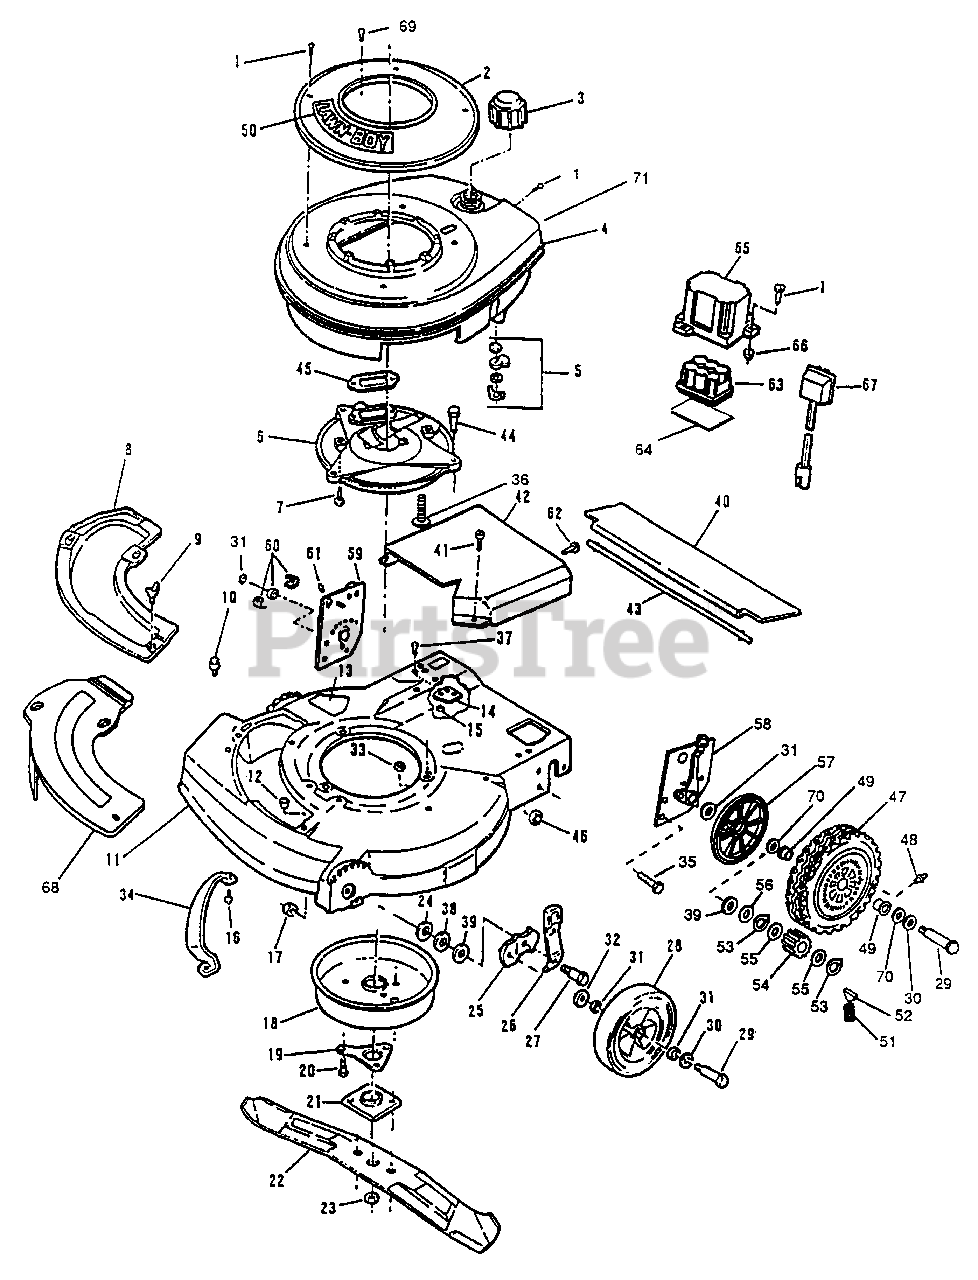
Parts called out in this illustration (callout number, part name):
1	Screw
2	Starter Base & Nut Assembly
3	Fuel Cap
4	Shroud-Engine (Inc. 5)
5	Fuel Shut-Off Assembly
6	Plate Muffler
7	Screw-Muffler Plate To Block
8	Cover Plate
9	Wing Screw
10	Screw-Plate & Chute Mounting
11	Housing Assembly (Inc. 12-13)
12	Grommet
13	Decal-Blade Contact Warning
14	Bolster-Housing
15	Nut-Bolster To Housing
16	Screw
17	Nut
18	Muffler Cover Assembly
19	Support-Crankshaft
20	Screw-Muffler To Muffler Plate
21	Collar & Plate Assembly
22	Blade-21"
23	Nut-Blade
24	Washer
25	Bracket-Wheel Height Adjust
26	Knob & Spring Assembly
27	Bolt-Shoulder
28	Wheel-Front
29	Bolt-Wheel
30	Washer-Flat
31	Washer-Felt
32	Washer
33	Nut-Muffler Plate To Housing
34	Toe Bar
35	Screw-Handle Bracket
36	Screw-Muffler Plate To Block
37	Screw-Bolster To Housing
38	Washer-Shim-Wheel Height Adjust Bracket
39	Washer-Shim-Wheel Height Adjust Bracket
40	Shield-Trailing
41	Screw-Drive Cover Mounting
42	Cover-Drive
43	Rod-Trailing Shield
44	Screw-Muffler Plate To Housing
45	Gasket-Exhaust
46	Locknut-Hdl. Brkt. To Housing
47	Rear Wheel (Inc. 48-49)
48	Lube Fitting
49	Bushing-Wheel
50	Applique-Starter Base
51	Spring
52	Key
53	Retaining Ring
54	Pinion
55	Spacer
56	Washer
57	Cover-Rear Wheel
58	Height Adjuster Assembly-L.H. (Inc. 60-61)
59	Height Adjuster Assembly-R.H. (Inc. 60-61)
60	Bearing & Retainer Assembly
61	Fitting
62	Screw
63	Battery Pack Assy (Inc. 64)
64	Pad-Battery
65	Cover-Battery
66	Grommet-Battery Mounting
67	Battery Charger Assembly
68	Mulch Plate Accessory
69	Screw-Starter Mounting
70	Washer-Felt
71	Decal-Fuel Mix
